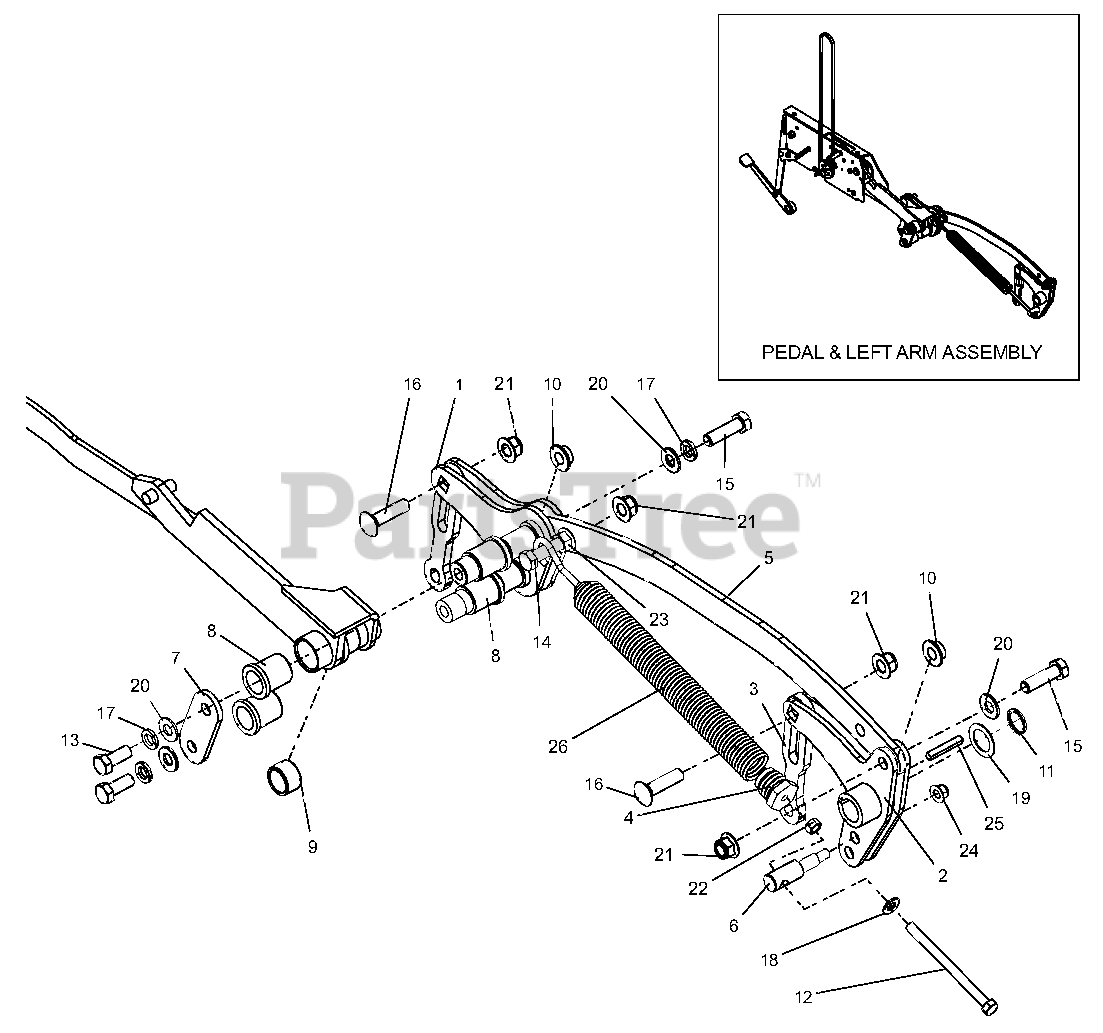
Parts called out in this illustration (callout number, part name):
1	WLDMT, DECK ARM
2	WLDMT, DECK LIFT PROSTANCE
3	LINK, DECK LIFT
4	PLUG, SPRG
5	ARM, DECK LIFT
6	TRUNION, DECK LIFT
7	PLATE, LIFT LINK ATTACH
8	BSHG-FLG 1.00X1.25X1.5X1.5
9	BSHG, 1.00 X 1.25 X .75
10	BSHG, FLANGE .515 X .750 X .420 X 1.12
11	RG-RTNG-EXT 1.00X.078 REV
12	BLT-HEX .38-16X5.0 GR5 FTD YWZ
13	BLT-HEX .50-13 X 1.25 GR5 YWZC
14	BLT-HEX .38-16X5.00 GR5 YWZC
15	BLT-HEX .50-13 X 1.75 GR5 YWZC
16	BLT-RDHDSQNK .50-13 X 2.00 G5 Y
17	NUT-SPLK-FLG .50-13 YWZC
18	WSHR-FL-STL .406 X .812 X .065 YWZ
19	WSHR-FL-STL 1.010X 1.505 X .062 YWZC
20	WSHR-FL-STL .531 X 1.06 X .095 YWZC
21	NUT-LK-NYL-FLG .50-13 YWZC
22	NUT-HEX .38-16 YWZC
23	NUT .50-13 WIZ FLANGE
24	NUT-LK-NYL-FLG .38-16 YWZC
25	KEY-STR .25 X 1.75 X .25
26	SPRG, DECK LIFT
